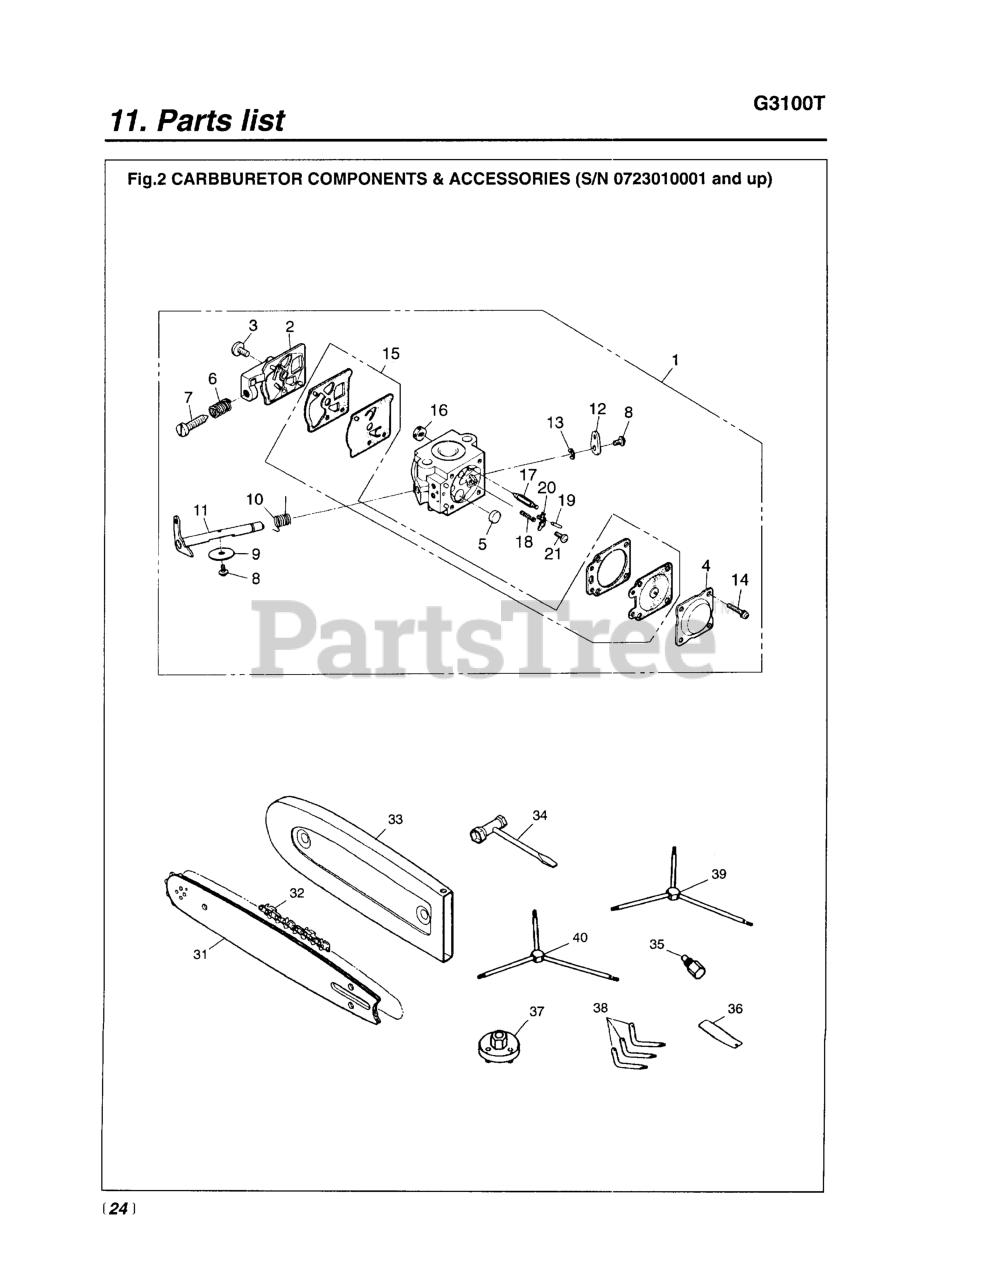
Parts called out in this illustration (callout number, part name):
1	CARBURETOR ASSY
2	PUMP COVER
5	PLUG, WELSH
6	SPRING, IDLE
8	SCREW (RPLS 3310-81360)
10	SPRING, RETURN
11	SHAFT ASSEMBLY
14	SCREW ASSEMBLY
15	GASKET KIT
17	VALVE, INLET
18	SPRING (USE 2867-81270)
19	PIN, METERING LEVER
20	LEVER
31	BAR 14
33	PROTECTOR (14.5
34	WRENCH, PLUG
36	GAUGE (TOOL)
37	WRENCH (TOOL)
38	WRENCH (TOOL)
40	HEX WRENCH (TOOL)
